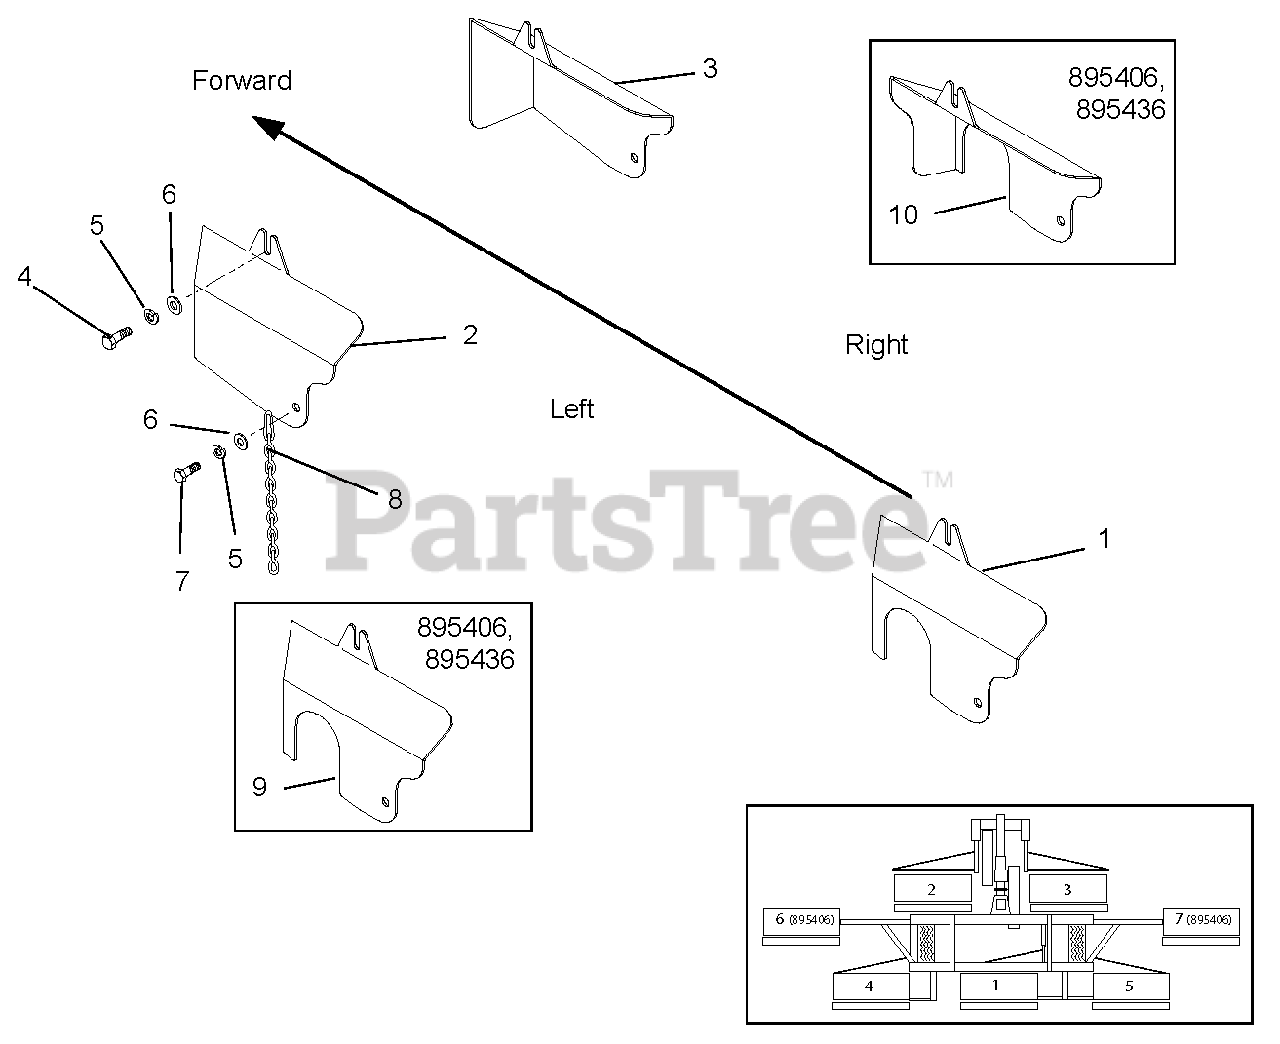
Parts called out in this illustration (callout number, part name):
1	Weldment, Belt Guard Center Rear – Unit 1
2	Weldment, Belt Guard Outside Left – Units 2 & 4 (895405, 435), Unit 2 (895406, 436)
3	Weldment, Belt Guard Outside Right – Units 3 & 5 (895435), Unit 3 (895436)
4	Cap Screw, Hex Head .312 x .75
5	Washer, Lock .312
6	Washer, Flat .312
7	Cap Screw .312-18 x 1.25
8	Chain, 8-LInk
9	Weldment, Belt Guard Outside Left – Unit 4 (895406, 436 Only)
10	Weldment, Belt Guard Outside Right – Unit 5 (895406, 436 Only)
